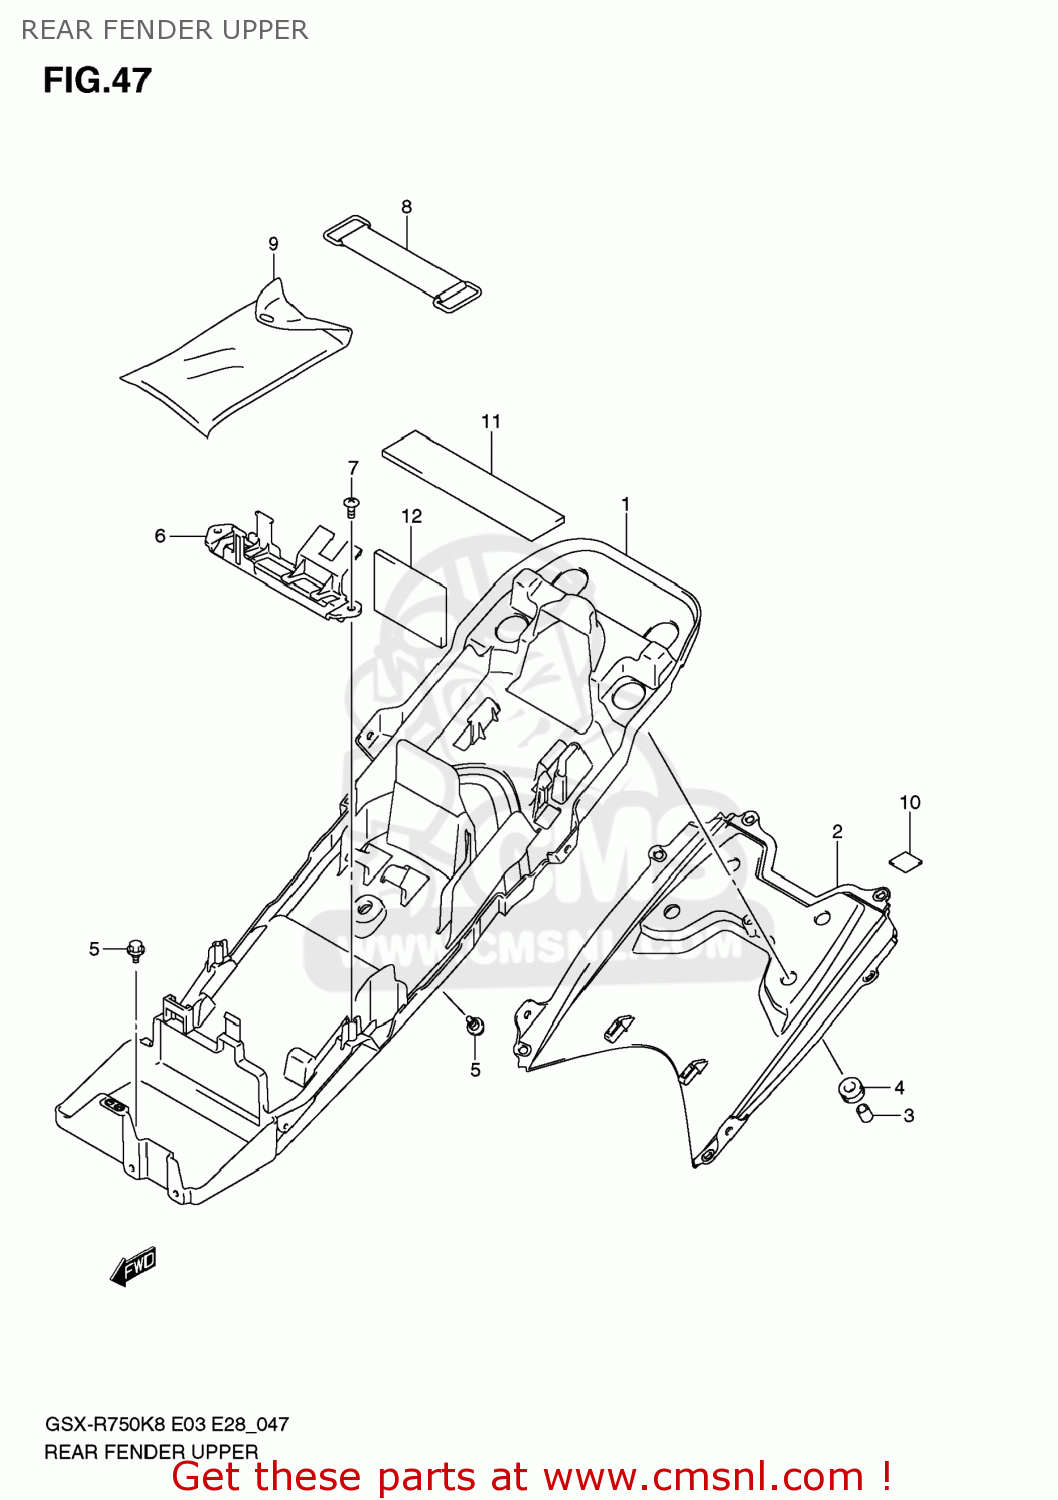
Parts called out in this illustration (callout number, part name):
1	FENDER,RR FR
2	COVER,RR FENDER FR
3	SPACER(6.5X9X13.5)
4	CUSHION
5	BOLT
6	BRACKET,ELECTRIC PARTS HOLDER
7	SCREW
8	BAND
9	TOOL ASSY
10	CUSHION,RR COVER NO.2
11	PROTECTOR,20X9
12	CUSHION,RR FENDER
